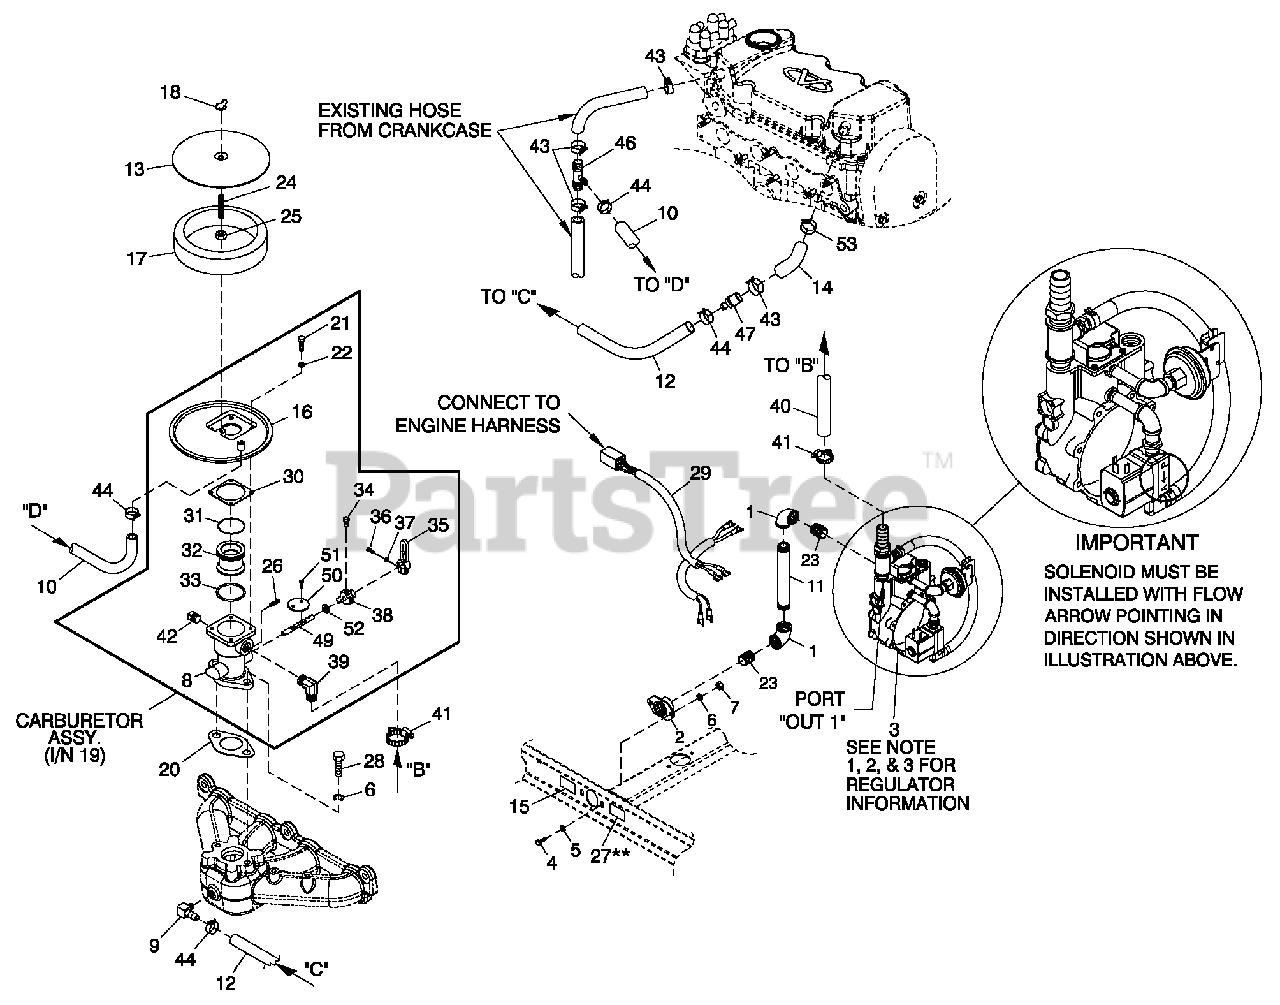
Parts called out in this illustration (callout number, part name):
1	ELBOW 90D3/4NPT
2	FLANGE FUEL INLET
3	FUEL REG. REWORK 1.6L 3600 '07 (3600RP M )
4	SCREW HHC M 8-1.25 X 20 G8.8
5	WASHER FLAT 5/16 ZINC
6	WASHER LOCK M 8-5/16
7	NUT HEX M8-1.25 G8 YEL CHR
8	BODY CARBURETOR ASSE M BLY
9	BARBED EL 90 1/8 NPT X 3/8
10	HOSE 3/8 ID LOW PRES OIL/WATER (16" LG)
11	NIPPLE PIPE 3/4 NPT X 6
12	HOSE 3/8 ID LOW PRES OIL/WATER (12" LG)
13	COVER AIR CLEANER
14	HOSE BREATHER 1.6L
15	DECAL INLET PRESSURE
16	ADAPTER CARB. TO AIR CLNR
17	FILTER ELE M ENT
18	NUT WING 1/4-20 NYLK
19	ASSY CARBURETOR 1.6L 3600RP M
20	CARBURETOR GASKET
21	SCREW PPH M M 5-0.8 X 12 ZNC
22	WASHER LOCK M 5
23	NIPPLE CLOSE 3/4X1.375
24	STUD TH 1/4-20 X 3 G2 ZNC FULL
25	NUT HEX 1/4-20 STEEL
26	PIN SPRING 3/16X5/8
27	DECAL FUEL INLET NG
28	SCREW HHC 5/16-18 X 1 G5
29	HARNESS FUEL JU MPER SINGLE REG
30	GASKET AIR CLEANER ADAPTER
31	O-RING 2-028 1.38 X 1.50 X .06
32	VENTURI 20 MM (3600RPM)
33	O-RING 29.82X2.62
34	SCREW THROTTLE PIN STOP
36	SCREW HH M #10-32X5/8
37	WASHER LOCK #10
38	LEVER THROTTLE STOP
39	BARBED EL 90 3/8 NPT X 5/8
40	HOSE 5/8 ID LPG &NG (12" LG)
41	CLAM P HOSE#10.56-1.06
42	PLUG STD PIPE 1/4 STEEL SQ HD
43	CLA M P HOSE BAND 1.0"
44	CLAM P HOSE BAND .63
46	HOSE BARB REDUCRTEE 3/4M-3/8M
47	PCV VALVE 2.5L FORD
49	SHAFT THROTTLE 1.5L
50	THROTTLE VALVE PLATE 27 M M
51	SCREW RH M S 6-32X1/4 ZINC
52	SEAL SHAFT COVER
53	CLAM P HOSE BAND .88"
